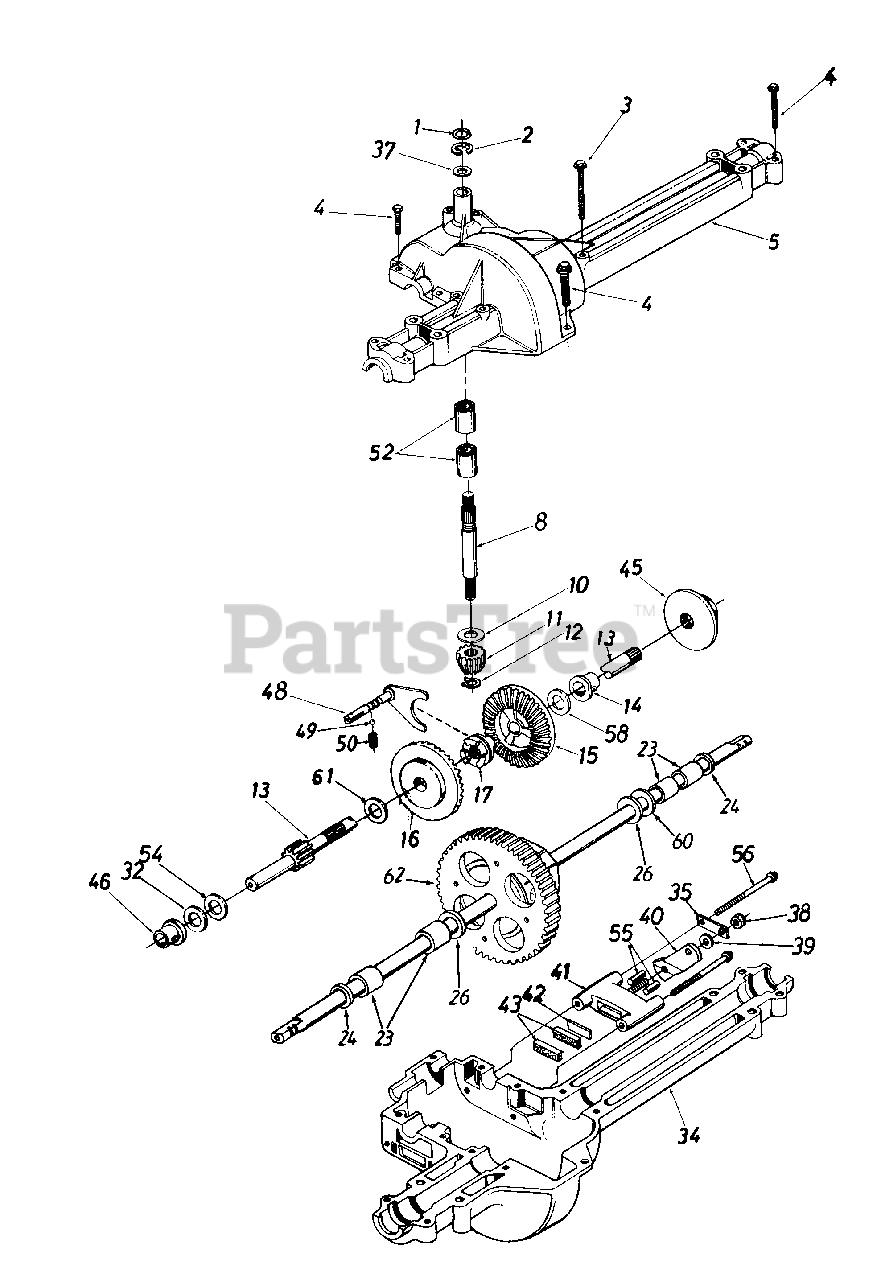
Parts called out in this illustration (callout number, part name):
1	Wire Ring
2	"E"-Ring
3	Hex Wash. TT-Tap Scr. 1/4-20 x 1.75" Lg.
4	Hex Tap Scr. 1/4-20 x 1.25" Lg.
5	Upper Housing
8	Input Shaft
10	Thrust Washer 5/8" I.D. x 1.25" O.D.
11	Pinion Input 14T
12	Retaining Ring
13	Drive Shaft - R.H. Brake
14	Flange Brg. 5/8" I.D. x 3/4" Lg.
15	Bevel Gear 42T Small I.D.
16	Bevel Gear 42T Large I.D.
17	Clutch Collar
21	Pan Head Scr. 1/4-20 x .50" Lg. w/Patch
23	Sleeve Bearing 3/4" I.D. x 1.0" Lg.
24	Oil Seal 3/4" I.D.
26	Fl-Wash. .760" I.D. x 1.5" O.D.
32	Washer
34	Lower Housing
35	Anti-Rotation Brkt.
37	Washer
38	Hex Nut 5/16-24 Thd.
39	Fl-Wash. .344" I.D. x .875" O.D.
40	actuating Arm
41	Brake Yoke
42	Puck Plate
43	Brake Puck
45	Brake Disc
46	Flange Bearing 5/8" I.D. x 15/16" Lg.
48	Shift Fork Ass'y.
49	Ball Detent .250" Dia.
50	Spring Detent
52	Needle Brg. 5/8" I.D. x 1/2" Lg.
54	Fl-Wash. 5/8" I.D. x 1" O.D. x .020 Thk.
55	Actuating Pin 5/16" Dia.
56	Hex Wash Hd. Self-Tap Scr. 1/4-20 Thd.
58	Fl-Wash. 5/8" I.D. x 1" O.D. x .020 Thk.
60	Washer
61	Thrust Washer
62	Differential Ass'y.
